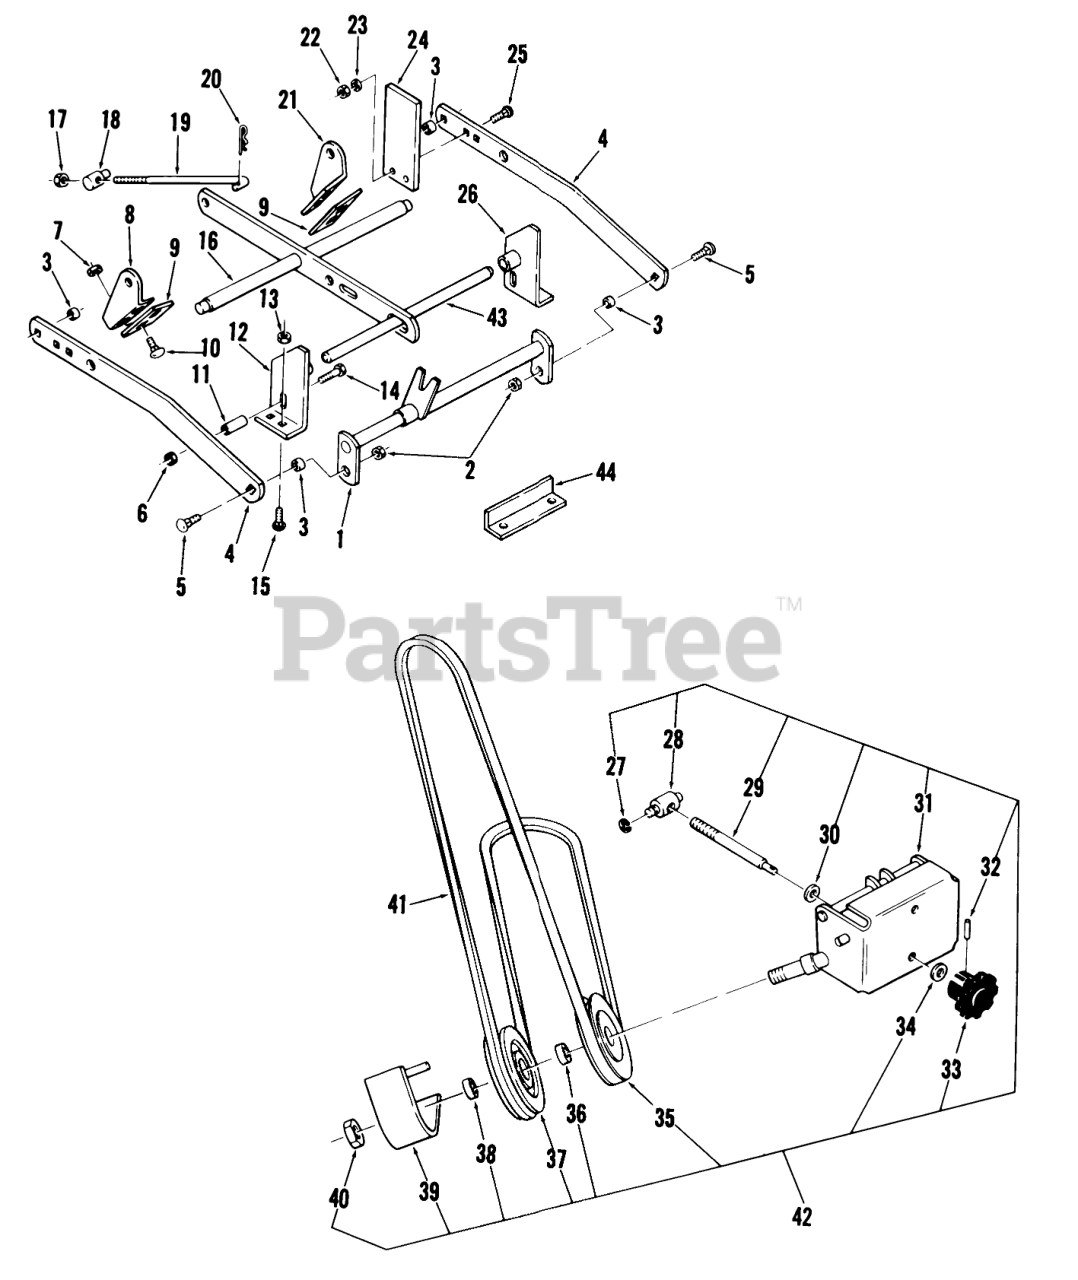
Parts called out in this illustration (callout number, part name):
1	Hitch
2	LOCKNUT-FLANGE
3	SPACER
4	Bar Draft
5	Bolt
6	Nut
7	Nut
8	Bracket-Rt. Rear
8	Bracket-R.H.
9	PLATE
10	Bolt
11	SPACER-BEARING
12	Bracket-R.H.
13	Nut
14	CARRIAGE BOLT -4
15	Bolt-Carriage
16	Leveler Ass-y.
17	NUT
18	TRUNNION-LIFT
19	ROD-LIFT
19	ROD-LEVELER
20	Hairpin
21	Bracket-L.H. Rear
21	Bracket-L.H.
22	Nut
23	Collar
24	BUMPER
25	Bolt-Carriage
26	Bracket-L.H.
27	RING-RETAINING
28	TRUNNION-DOUBLE
29	ROD ADJ
30	Washer
31	Front Support
32	PIN-ROLL
33	KNOB-ADJUSTMENT
34	WASHER-SPRING
35	Pulley-V
36	SPACER
37	PULLEY-FLAT IDLER
38	SPACER-OUTER
39	Belt Cover
40	Nut 3/4-16 MF
41	V-BELT
42	ASM-SUPPORT,IDLER
43	Front Shaft
44	ANGLE
